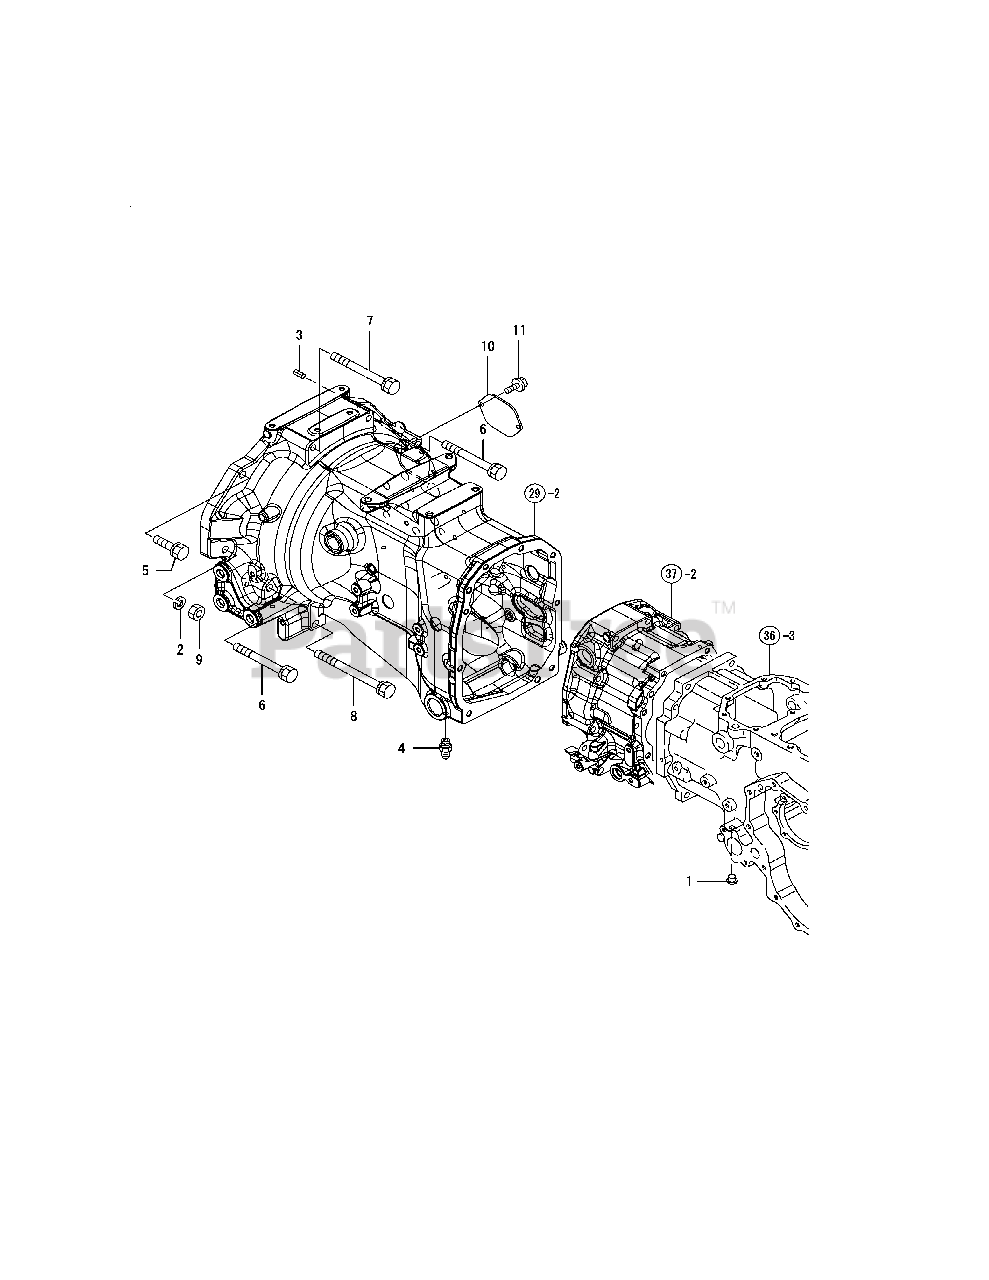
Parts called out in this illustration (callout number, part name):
2	SPRING WASHER 12
3	SPRING PIN 8X18
4	NIPPLE PT1/8,GREASE
11	BOLT M 8X 16 PLATED
